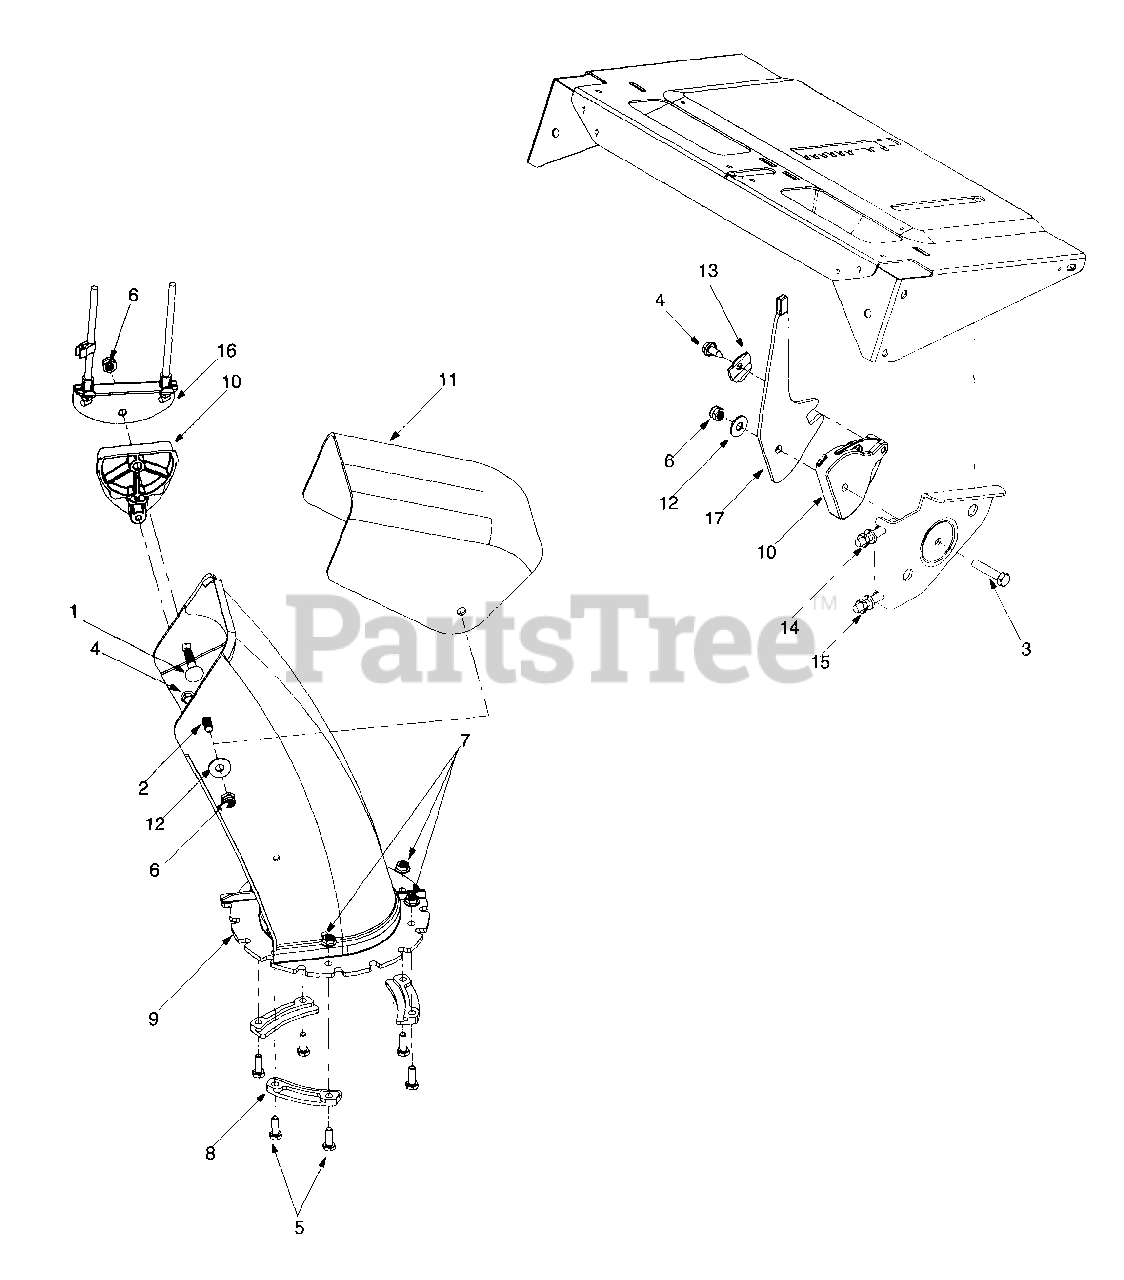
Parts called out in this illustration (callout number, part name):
1	Carriage Bolt: 5/16-18 x 1.5"
2	Carriage Bolt: 5/16-18 x 0.75"
3	Hex Bolt: 5/16-18 x 1.5 Gr. 5
4	Hex Washer Head AB Screw: 1/4-14 x 0.625"
5	Hex Bolt: 1/4-20 x 0.75"
6	Hex Lock Nut: 5/16-18
7	Flange Lock Nut
8	Chute Flange Keeper
9	Lower Chute
10	Chute Tilt Cable Guide
11	Upper Chute
12	5/16 Washer
13	Special Washer
14	Control Cable: Chute Deflector
15	Chute Deflector Cable w/Clip
17	Chute tilt Handle
